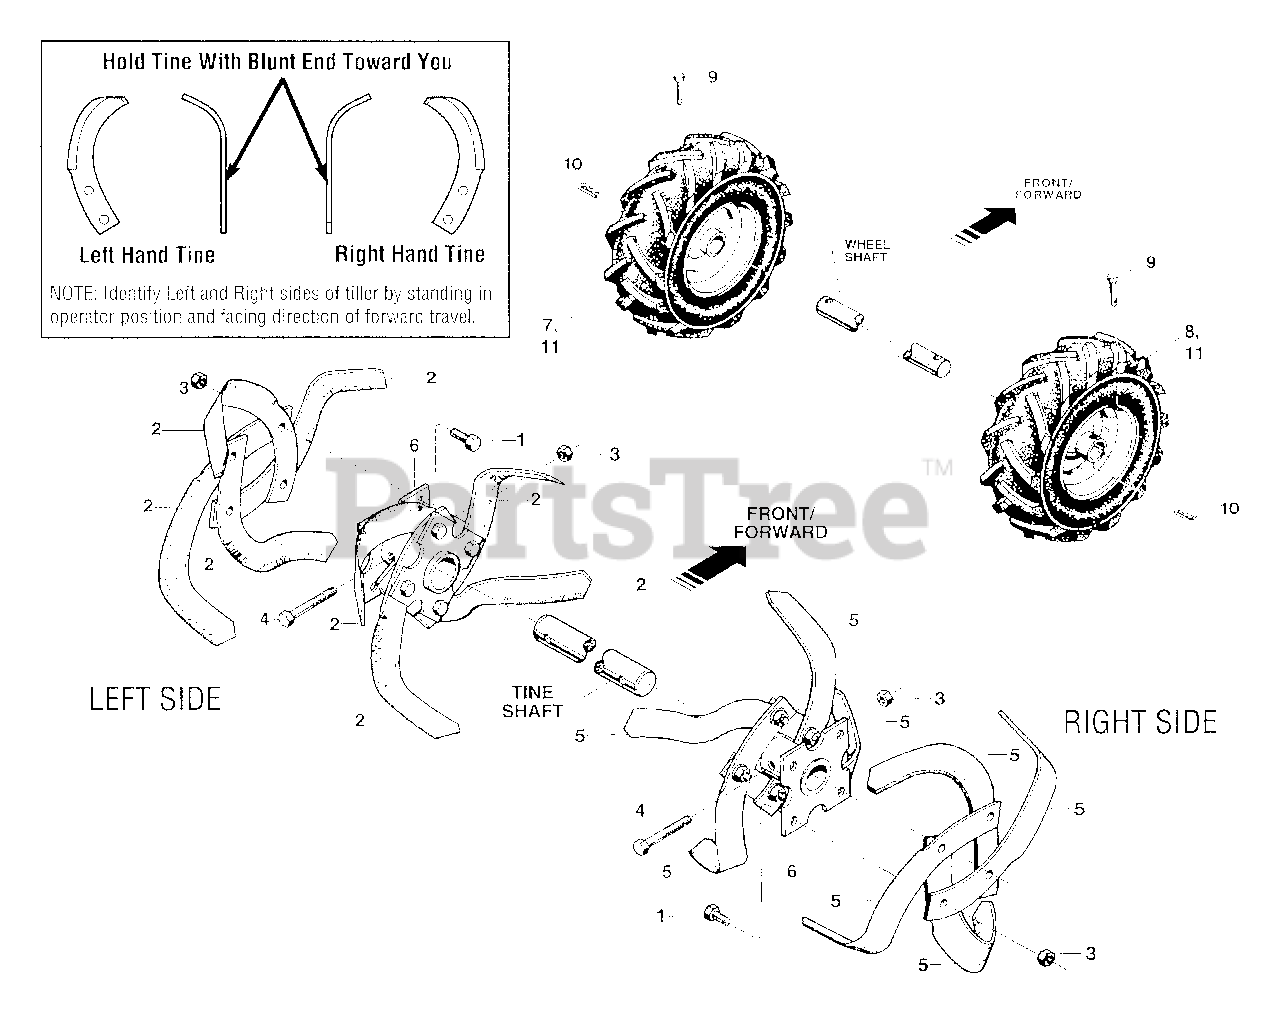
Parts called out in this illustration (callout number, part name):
1	Hex Hd. Screw, 3/8-16 x 1, Grade 5
2	Bolo Tine - Right Hand
3	Hex Lock Nut, 3/8-16
4	Hex Hd. Screw, 3/8-16 x 1-3/4
5	Bolo Tine - Left Hand
6	Tine Holder
7	Wheel & Tire Assy-Left Side
8	Wheel & Tire Assy-Right Side
9	Clevis Pin, .312" x 1-3/4"
10	Hair Pin Cotter
11	Wheel & Tire Assy
